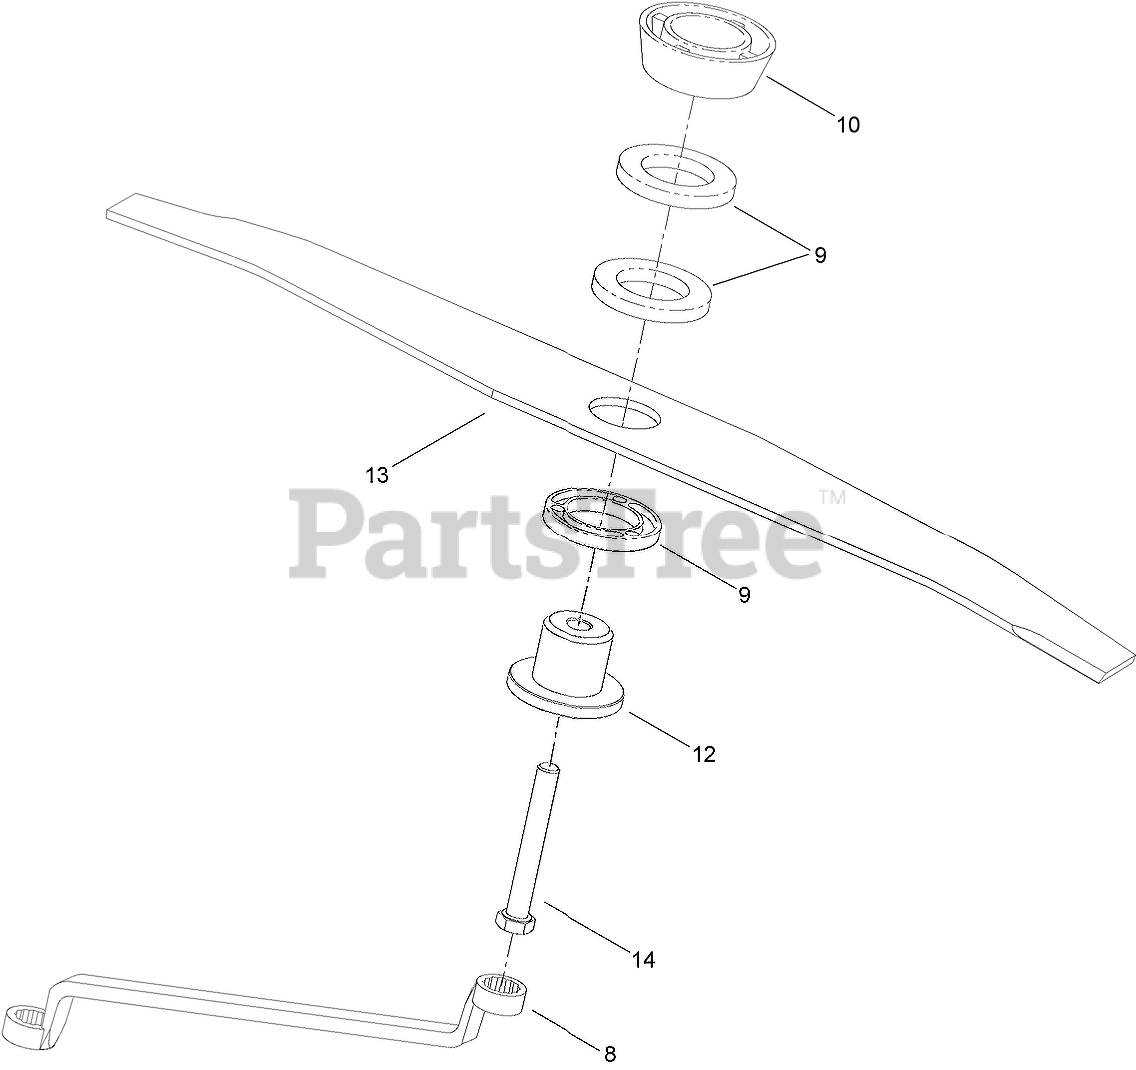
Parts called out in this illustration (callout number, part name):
8	SPANNER
9	SPACER-BLADE, ALUMINIUM
10	SPACER-DISTANCE
12	RETAINER-BLADE
13	BLADE
14	SCREW-SET
